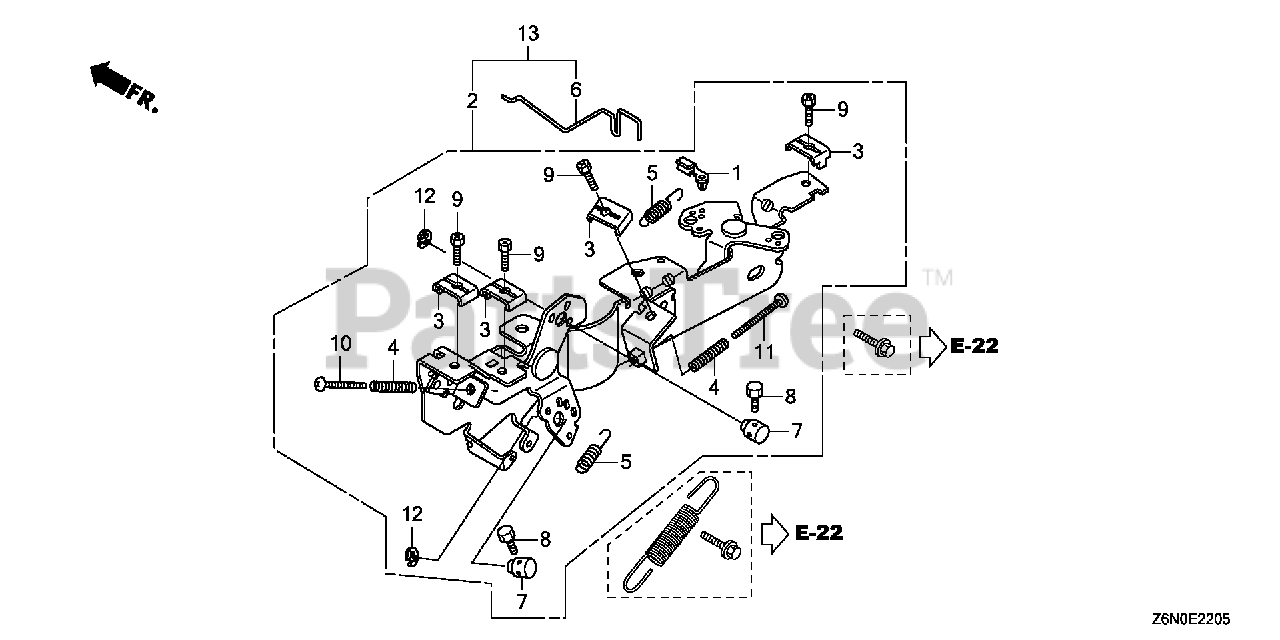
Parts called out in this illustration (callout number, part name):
1	JOINT, ROD
2	CONTROL ASSY.
3	HOLDER, CABLE
4	SPRING, CONTROL ADJUSTING
5	SPRING, CABLE RETURN
6	ROD, CHOKE CONTROL
7	HOLDER, CABLE
8	BOLT, RECESSED (4X6)
9	BOLT, RECESSED (5X16)
10	SCREW, PAN (5X30)
11	SCREW, PAN (5X40)
11	SCREW, PAN (5X45)
12	E-RING (5MM)
13	CONTROL KIT
